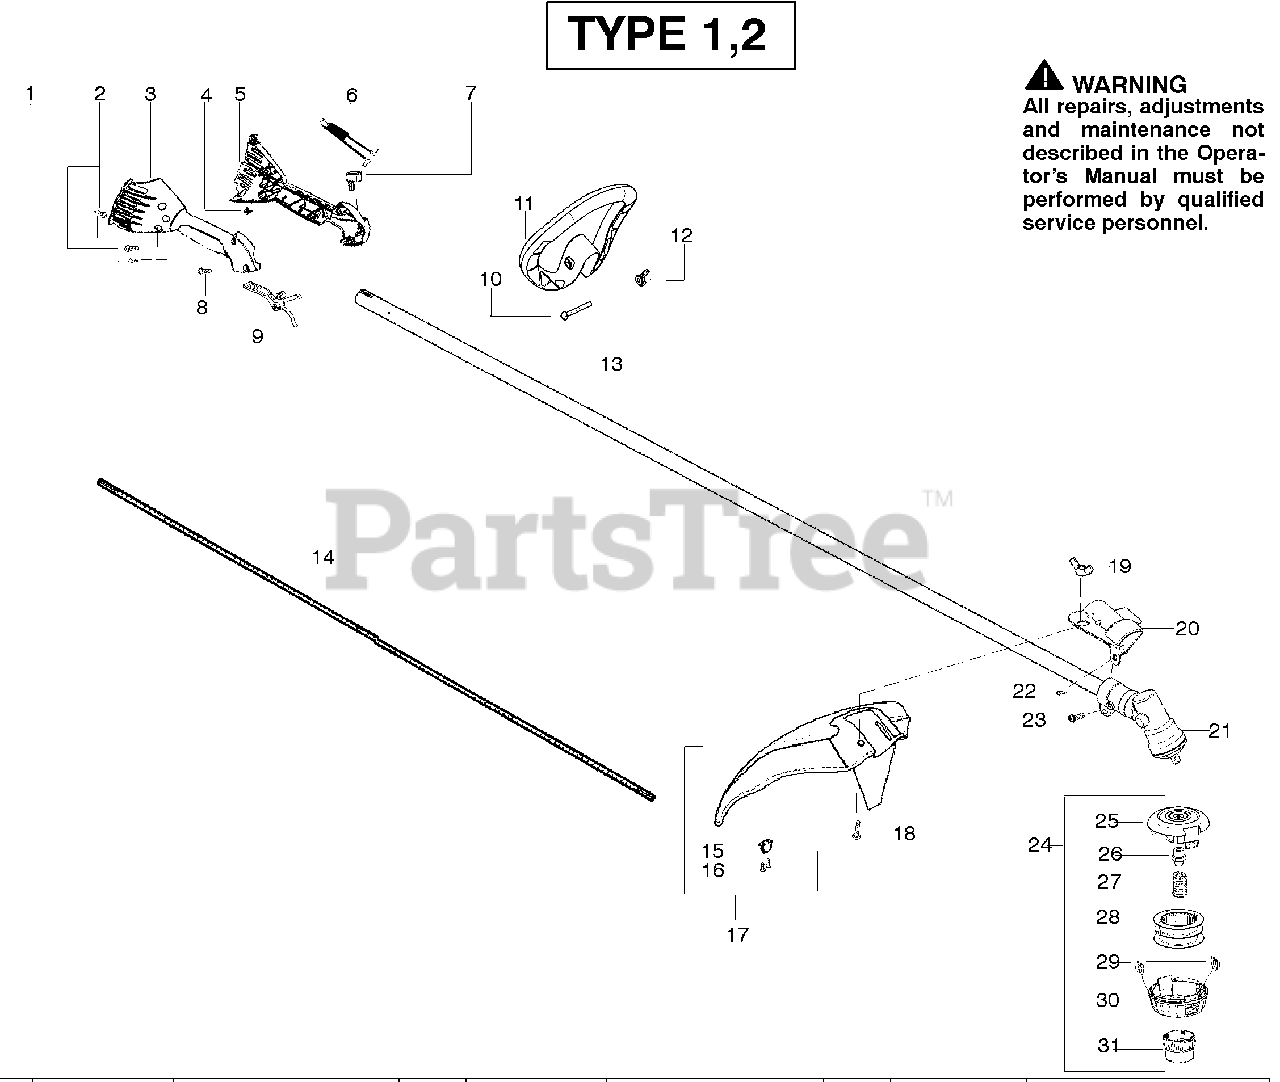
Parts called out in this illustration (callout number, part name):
1	Screw-alignment
3	Hsg.-Throttle right
4	Screw-Cable Retention
5	Hsg.-Left throttle
9	Lever-Throttle
11	Assy-Handle
12	Wingnut
17	Kit-Shield Assy.
19	Wingnut
20	Bracket-Shield
24	Assy-TNG VII
25	Housing
26	Adapter
27	Spring
28	Accy-Wound Spool
29	Eyelet
30	Cover
31	Knob
